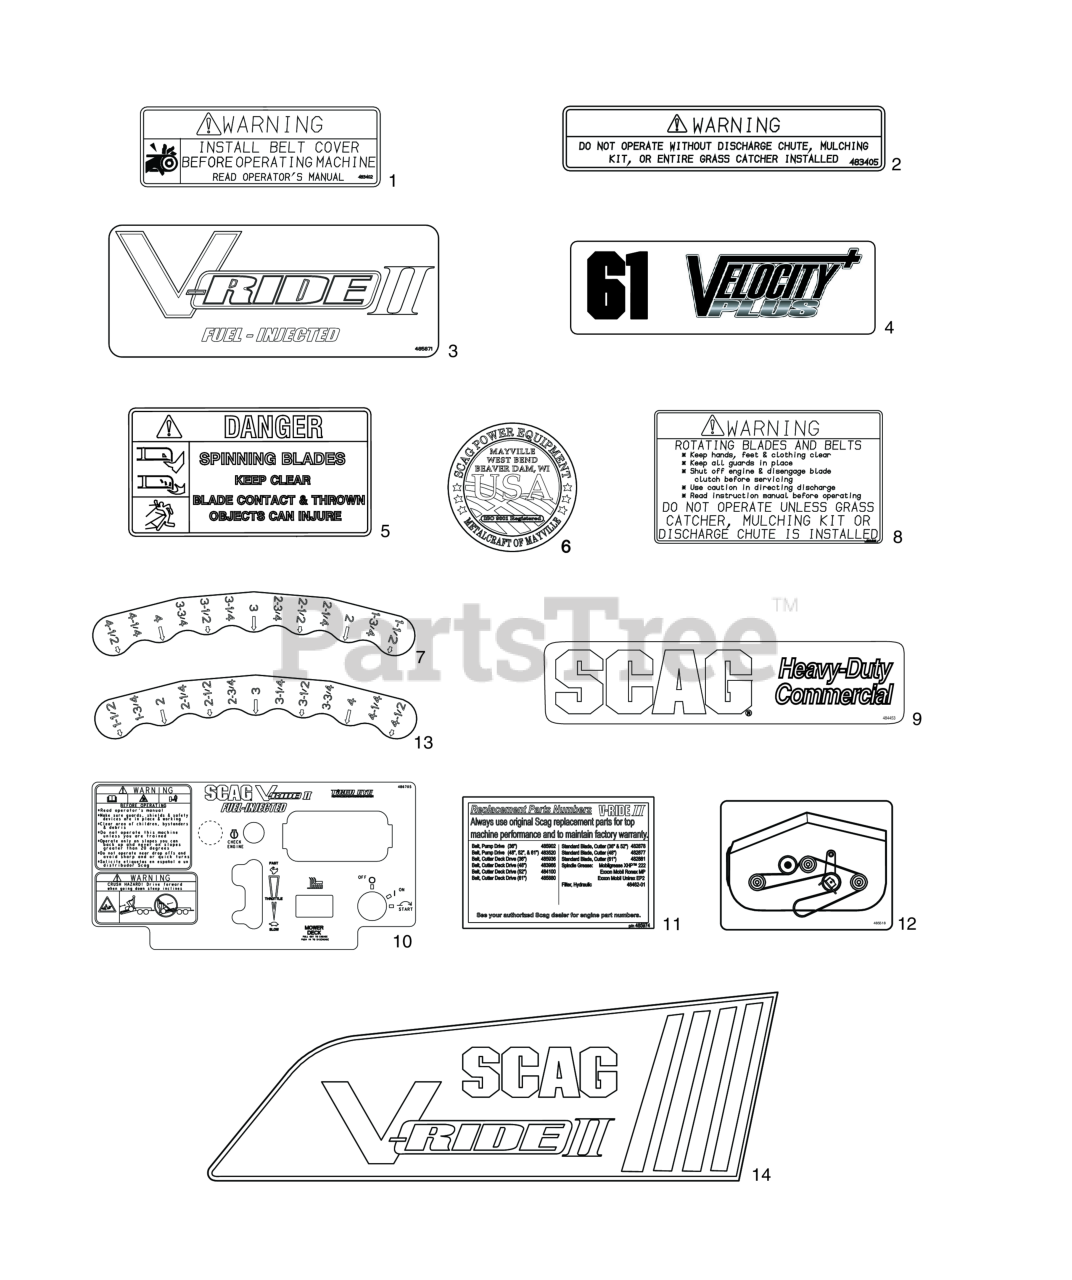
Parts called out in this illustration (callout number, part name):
1	Decal, Warning - Belt Cover
2	Decal, Warning-Discharge
3	Decal, Belt Cover
4	DECAL, VELOCITY PLUS - 61
5	Decal, Spinning Blades
6	Decal, Metalcraft - USA
7	Decal, Deck Height - Outer
8	Decal, Warning - Rotating Blades
9	Decal, Scag Heavy Duty Commercial
10	Decal, Instrument Panel - SVRII
11	Decal, SVRII Replacement Parts
12	Decal, Belt Routing - SVRII48V, SVRII52V & SVRII61V
13	Decal, Deck Height - Inner
14	Decal, Scag V-Ride II (Fuel Tank)
